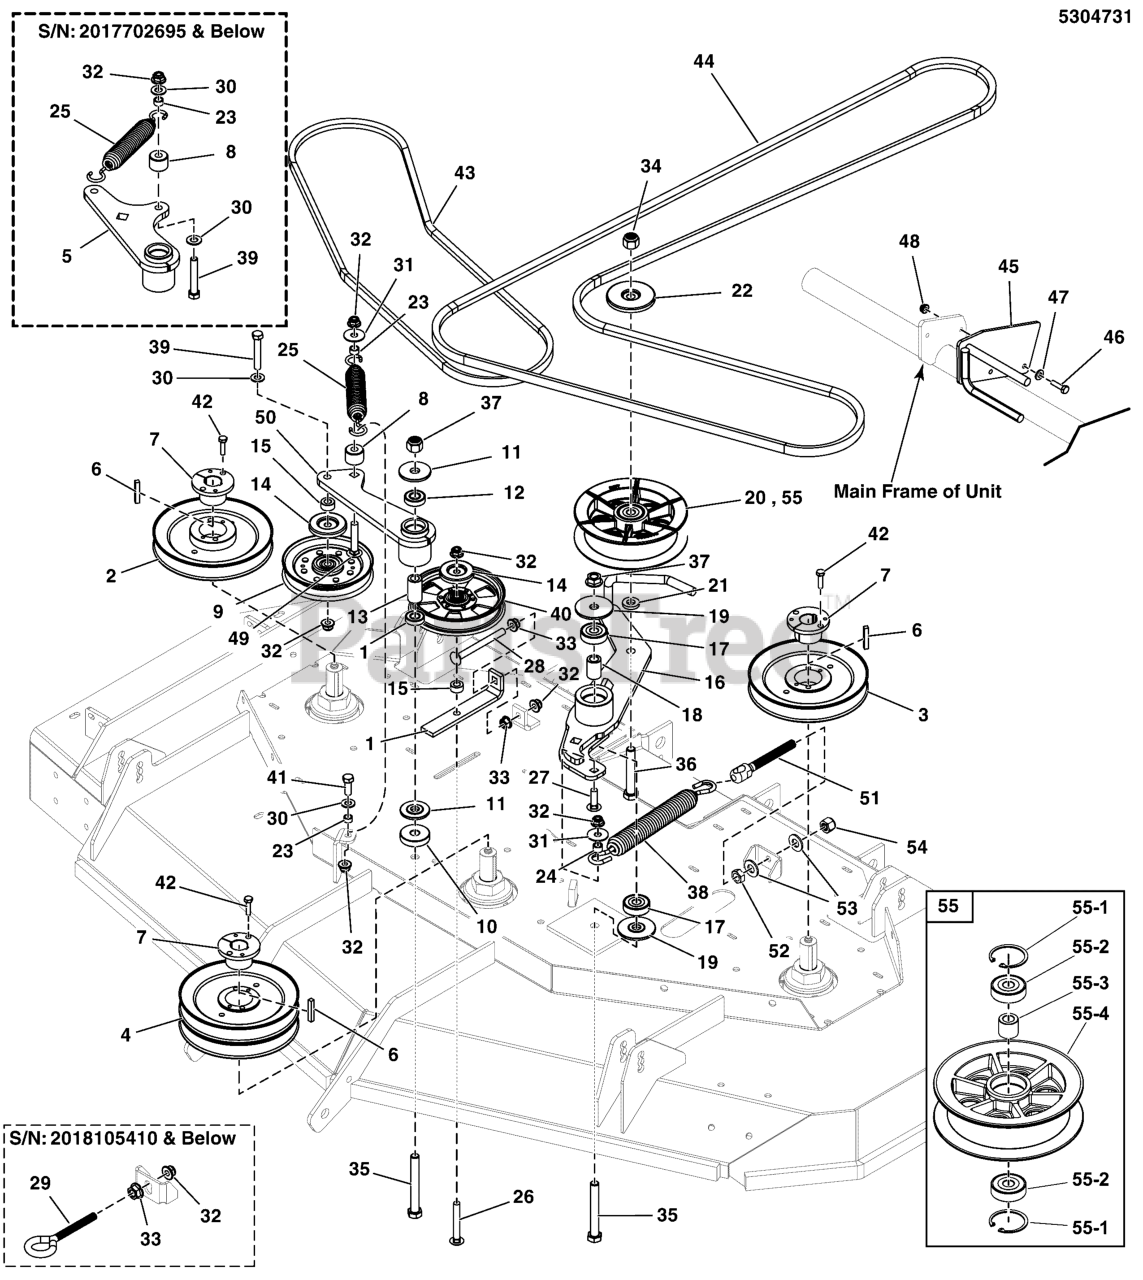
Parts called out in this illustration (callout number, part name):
1	PLATE, IDLER PUSHER, 72 - BLK
2	PULLEY, SPNDL, 8.37"OB, HQ BORE -RH
3	PULLEY, SPNDL, 8.37"OB, HQ BORE -LH
4	PULLEY, SPNDL, 8.37"OB-DBL, HQ BORE
6	KEY 1/4 SQ X 1 1/2 LONG
7	BUSHING, Tapered Hub
8	SPACER, .39 X 1.00 X .75, CZ
9	PULLEY, V-IDLER, 5"OD X 3/8", CZ, TE
10	SPACER, .52 X 1.75 X .420, CZ
11	SPACER, IDLER ARM, 1/2, PM
12	BEARING, BALL, AXLE
13	SPACER, .52 X .84 X 1.53, PM
14	SHIELD, PULLEY, 3/8"ID X 2"OD, CZ
15	SPACER, .39 X 1.00 X .63, CZ
16	WELD, IDLER ARM, DECK DRIVE - BLK
17	BEARING, 6203-1/2", SEALED
18	SPACER, .51 X .84 X 1.22, PM, CZ
19	SPACER, IDLER ARM, 1/2 X 2.25
21	SPACER, .52 X 1.00 X .22, PM, CZ
22	SHIELD, PULLEY, 1/2"ID X 2-7/8"OD, CZ
23	SPACER, .38 X .50 X .27, CZ
24	SPACER, .39 X .63 X .375M DOM CZ
25	SPRING-EXT, 1.04 ODX6.935LGX.148WR, BLK
26	BOLT, 3/8-16 X 2-1/2, CARRIAGE, GD5, CZ
27	BOLT, 3/8-16 X 1-1/2, CARRIAGE, GD5, CZ
28	BOLT, 3/8-16 X 4-1/2, CARRIAGE, GD5, CZ
29	EYE BOLT, 3/8-16 X 6, 3THRD, 1EYE, CZ
29	EYE BOLT, 3/8-16 X 5, 2.88THRD, 1EYE, CZ
30	WASHER, 3/8 SAE
31	WASHER, 3/8" Fender
32	NUT, 3/8 - 16 HEX NYLOCK FLANGE
33	NUT, 3/8-16 Hex Large Serrated Flange
34	NUT, 1/2-13 HEX NYLON LOCK
35	BOLT, 1/2-13 X 4" GD5 CZ
36	BOLT, 1/2-13 X 3-1/4, HEX HD, GD5, CZ (SV)
37	NUT, Hex Flange, Nylock, 1/2-13
38	SPRING, EXT1.22"ODX10.5"FLX.192"WIRE BLK
39	BOLT, 3/8-16 X 2-1/4" GD5 CZ
40	PULLEY, FLT IDLR, 6.0 X 1.0 X .38, CZ
41	BOLT, 3/8-16 X 1" GD5 CZ
42	BOLT, 1/4-20 X 1" GD5 CZ
43	BELT, B-SEC, 76.40 EL, ARAMID, WRPD
44	BELT, 5V/SPB, 153.70 EL, LG ARAMID, WRPD
45	WELD, CLUTCH BELT GUIDE - BLK
46	BOLT, 1/4-20 X 1" GD5 CZ
47	WASHER, 1/4 SAE
48	NUT, 1/4-20 Hex Nylock Flange
49	BOLT, 3/8-16 X 2, CARRIAGE, GD5, CZ
50	WELD, IDLER ARM, 2 BELT DRIVE - BLK
51	SPRING PULLER, 1/2-20, 5.00
52	NUT, 1/2-20 Hex Jam
53	WASHER, 1/2 SAE
54	NUT, 3/8 - 16 HEX NYLOCK FLANGE
55	PULLEY, IDLER, 5.50, CI
55-1	SNAP RING, Internal
55-2	BEARING, 6203-3RC3-1/2SRI2-Q
55-3	SPACER, .505 X .875 X .805, CZ
55-4	PULLEY HOUSING
